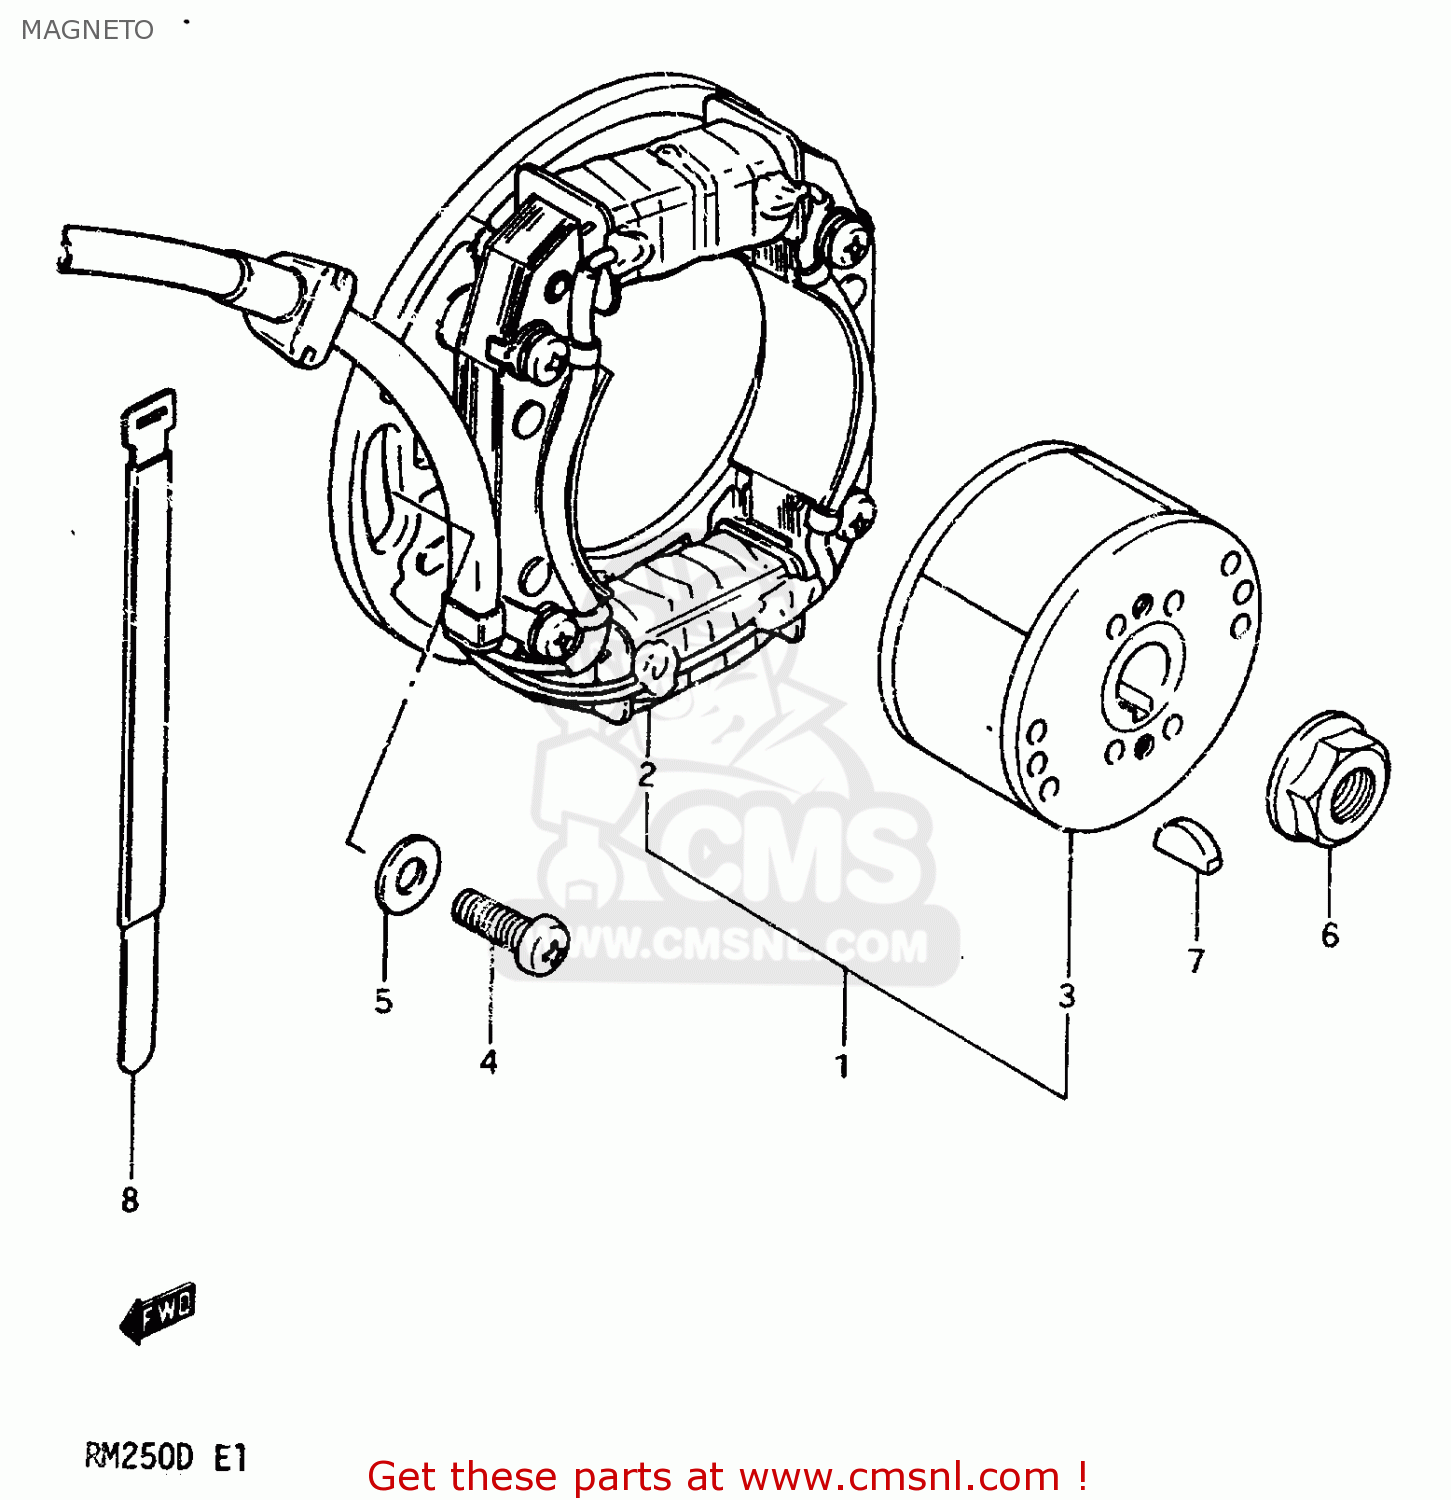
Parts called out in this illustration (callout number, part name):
1	STARTER ASSY
2	STARTER ASSY
3	ROTOR ASSEMBLY
4	SCREW
5	WASHER
6	NUT
7	KEY 4MM
8	CLAMP
